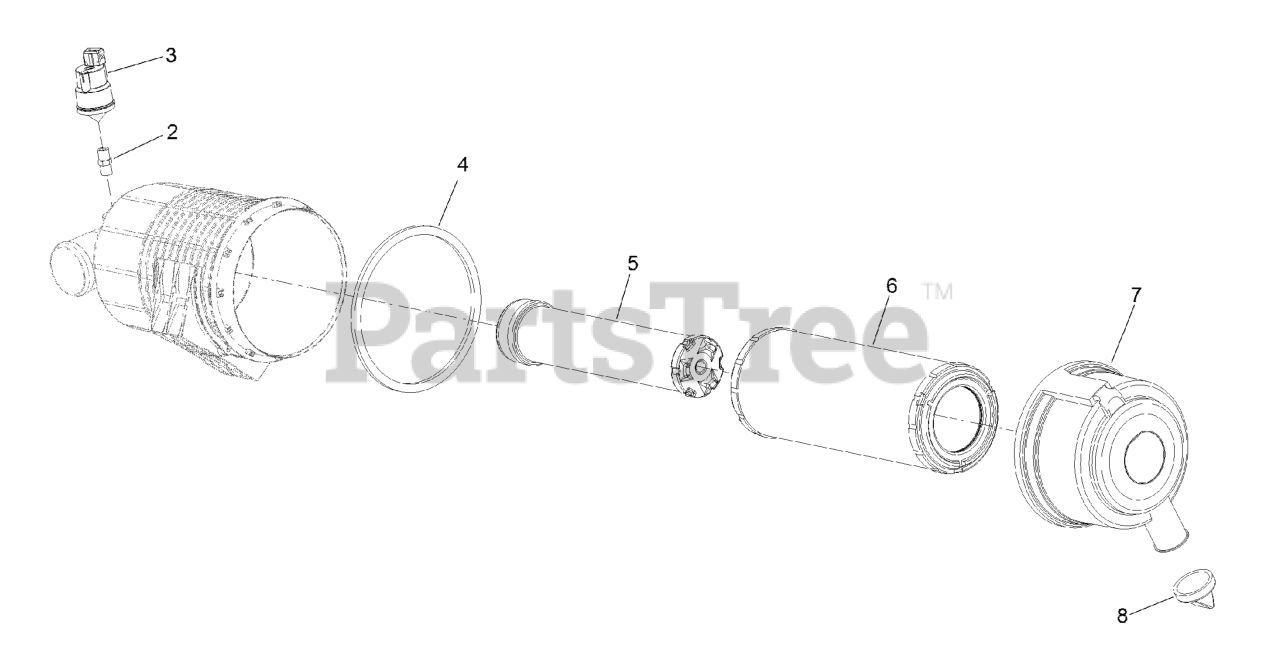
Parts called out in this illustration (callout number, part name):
2	NIPPLE-PIPE
3	INDICATOR-MINI
8	VALVE-VACUATOR
